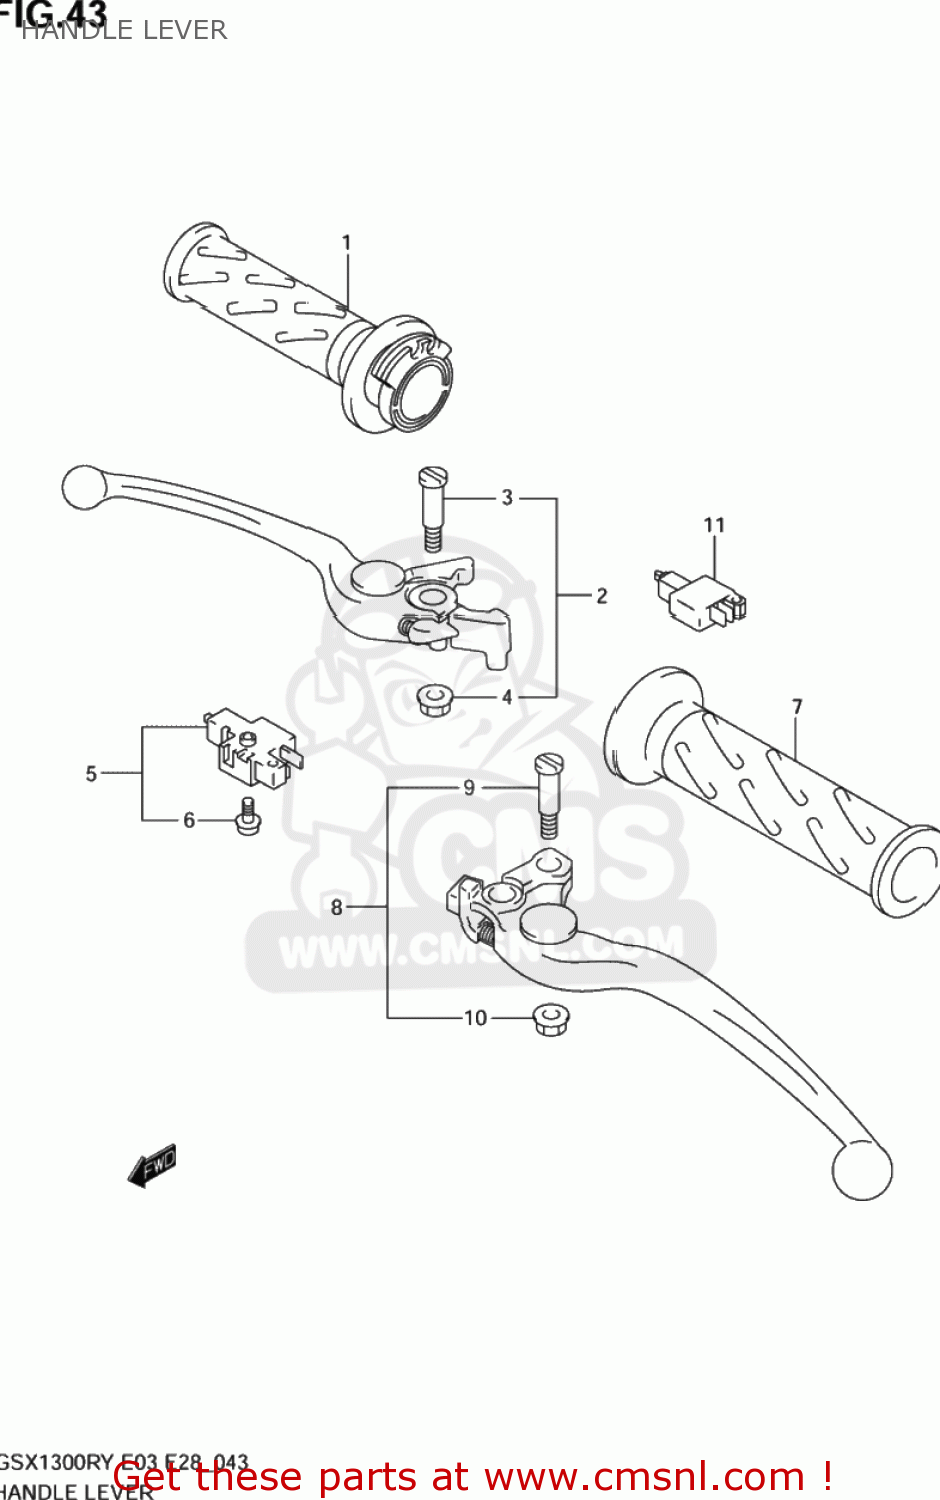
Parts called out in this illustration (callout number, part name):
1	GRIP,THROTTLE
2	LEVER ASSY,BRAKE
3	BOLT,LEVER PIVOT
4	NUT
5	SWITCH ASSEMBLY,STOP
6	SCREW
7	GRIP,LEFT
8	LEVER ASSEMBLY,CLUTCH
9	BOLT,LEVER PIVOT
10	NUT
11	SWITCH ASSY,CLUTCH
